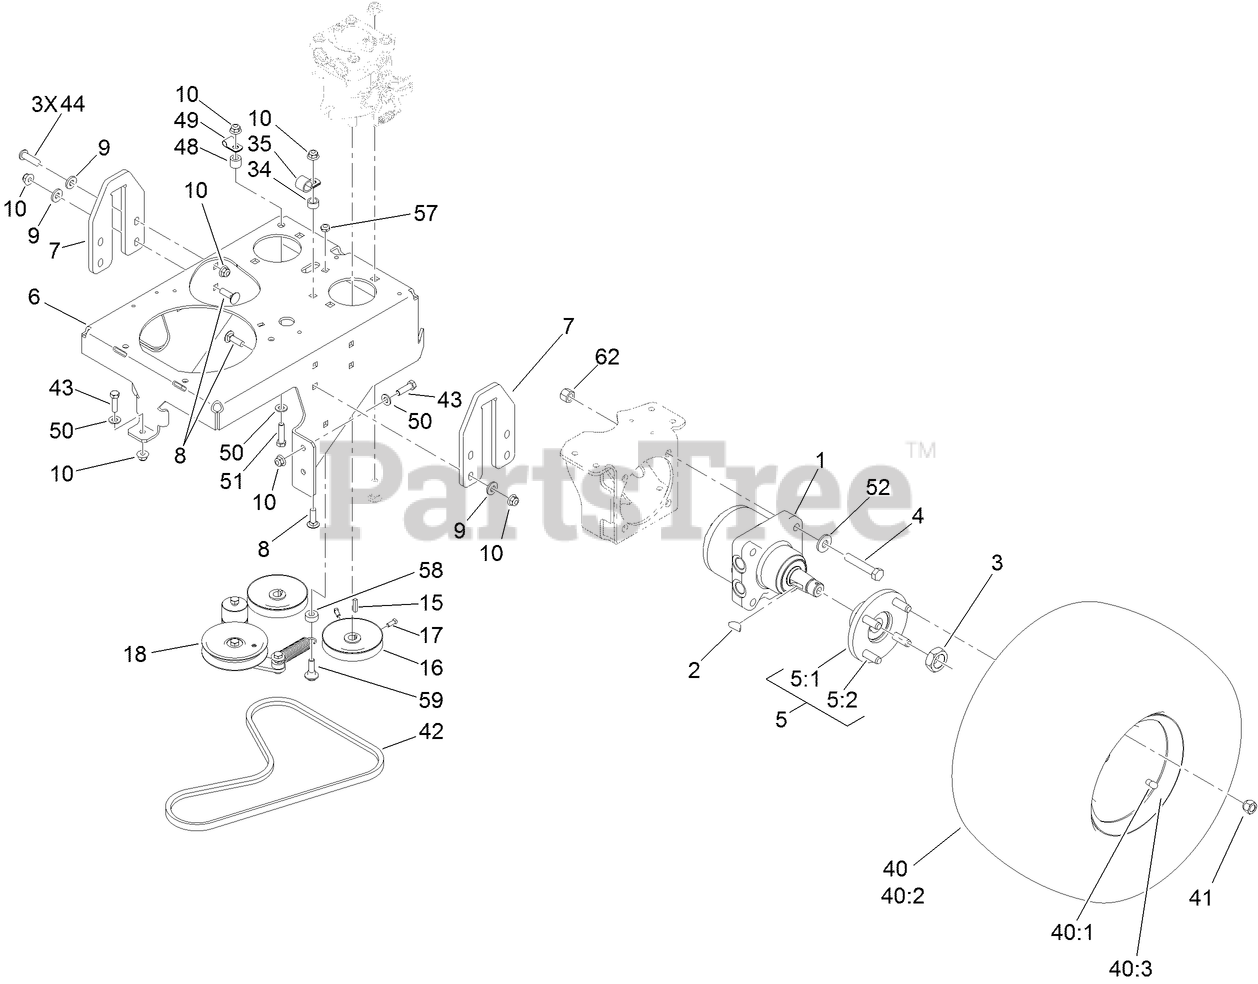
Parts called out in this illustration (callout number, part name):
1	MOTOR-WHEEL
2	KEY-WOODRUFF
3	NUT-LOCK
4	SCREW-HH
5	Wheel Hub / Stud ASM
5:1	HUB-WHEEL
5:2	STUD-TYPE, DRIVE
6	BASE-ENGINE
7	PLATE-LIFT
8	BOLT-CARR
9	WASHER-BELLEVILLE
10	NUT-HF, NI
16	PULLEY-PUMP
17	SCREW-SET
18	PUMP IDLER ASM
34	SPACER-WHEEL
35	CLIP-LOOM
40	WHEEL AND TIRE ASM
40:1	RIM-8 INCH, GRAY
40:3	STEM-VALVE
41	NUT-LUG
42	BELT-V, LOWER PTO
43	SCREW-HHF
44	SCREW-HSBH
48	SPACER
49	CLIP-TUBE
50	WASHER-FLAT
51	SCREW-HH
52	WASHER-SPRING
57	NUT-LOCK, NI
58	SPACER
59	SCREW-SHOULDER, HWH
62	NUT-LOCK, NI
